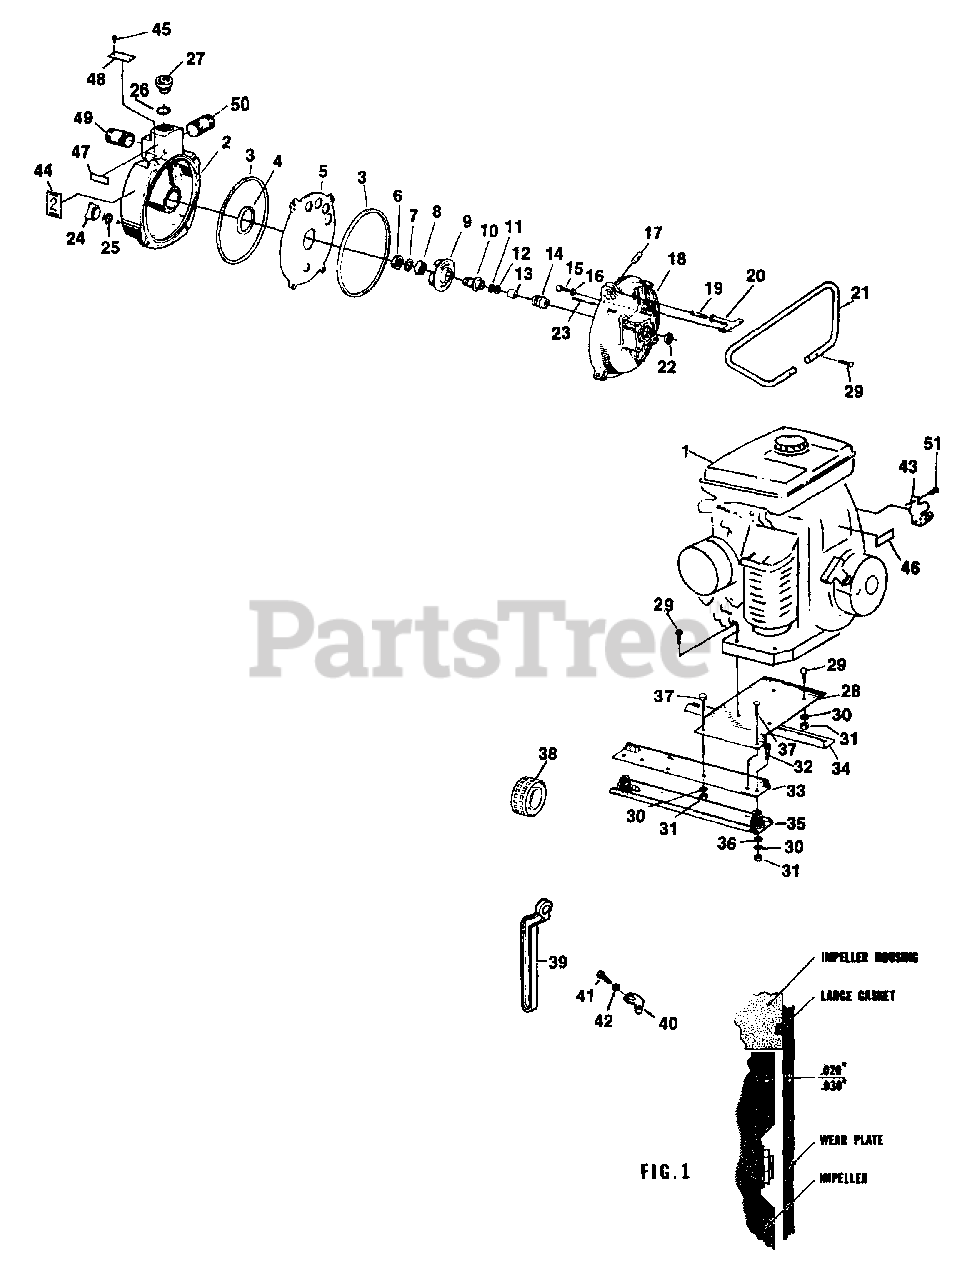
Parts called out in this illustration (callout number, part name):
2	HOUSING
3	GASKET-Large
4	GASKET-Small
5	PLATE-Wear
6	NUT
8	BUSHING-Tapered
9	IMPELLER
10	HUB-Impeller
11	SHIM, .010
12	SHIM, .015
13	SPACER- Crankshaft
14	SEAL ASSEMBLY
15	SCREW-Hex hd 5/16-24 x 2 1/4
16	WASHER-Sealing
17	PIVOT-Handle
18	HOUSING-Impeller
19	STUD-Handle
20	HANDLE-Disconnect
21	HANDLE-Carrying
22	SLINGER
23	PIN-Spirol
24	PLUG-Drain
27	PLUG-Wing
28	PLATE-Engine mounting
29	SCREW-5/16-18 x 1 1/2
30	WASHER-Lock, 5/16
31	NUT-5/16-18
32	SCREW-Cap hex hd 5/16-18 x 1"
33	ANGLE-Base, left side
34	ANGLE-Base, right side
35	SKID ASSEMBLY
36	WASHER-Flat, 5/16
37	SCREW, 5/16-18 x 3/4
38	STRAINER
39	WRENCH-Spanner
40	HOLDER-Spanner wrench
41	SCREW-Hex cap 1/4-20 x.5
42	WASHER-Flat 1/4
43	BRACKET-Lite
44	DECAL-Class
45	TACK-Metal
46	DECAL-Low oil
47	DECAL-Fill pump
48	PLATE-Warning
49	NIPPLE-2" x 2" long
50	NIPPLE-2" x 3 1/2" long
51	SCREW-#8-18 x 3/4"
